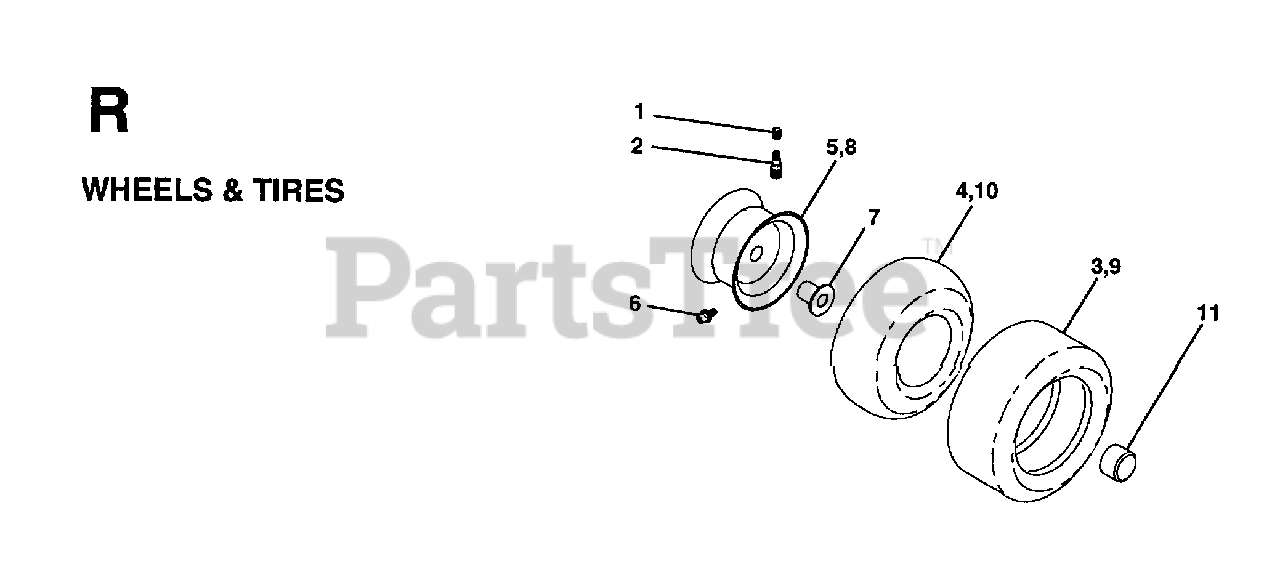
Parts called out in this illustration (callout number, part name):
1	VALVE CAP
2	VALVE STEM LT
3	TIRE HEAVY DUTY
4	TUBE.5.3/4.5/6
5	RIM ASM 6" FRONT SILVER
6	FITTING LT
7	BEARING T
8	RIM ASM 8" REAR SILVER
9	TIRE.TS.20X10-8
10	TUBE
11	CAP-HUB FRONT LT
